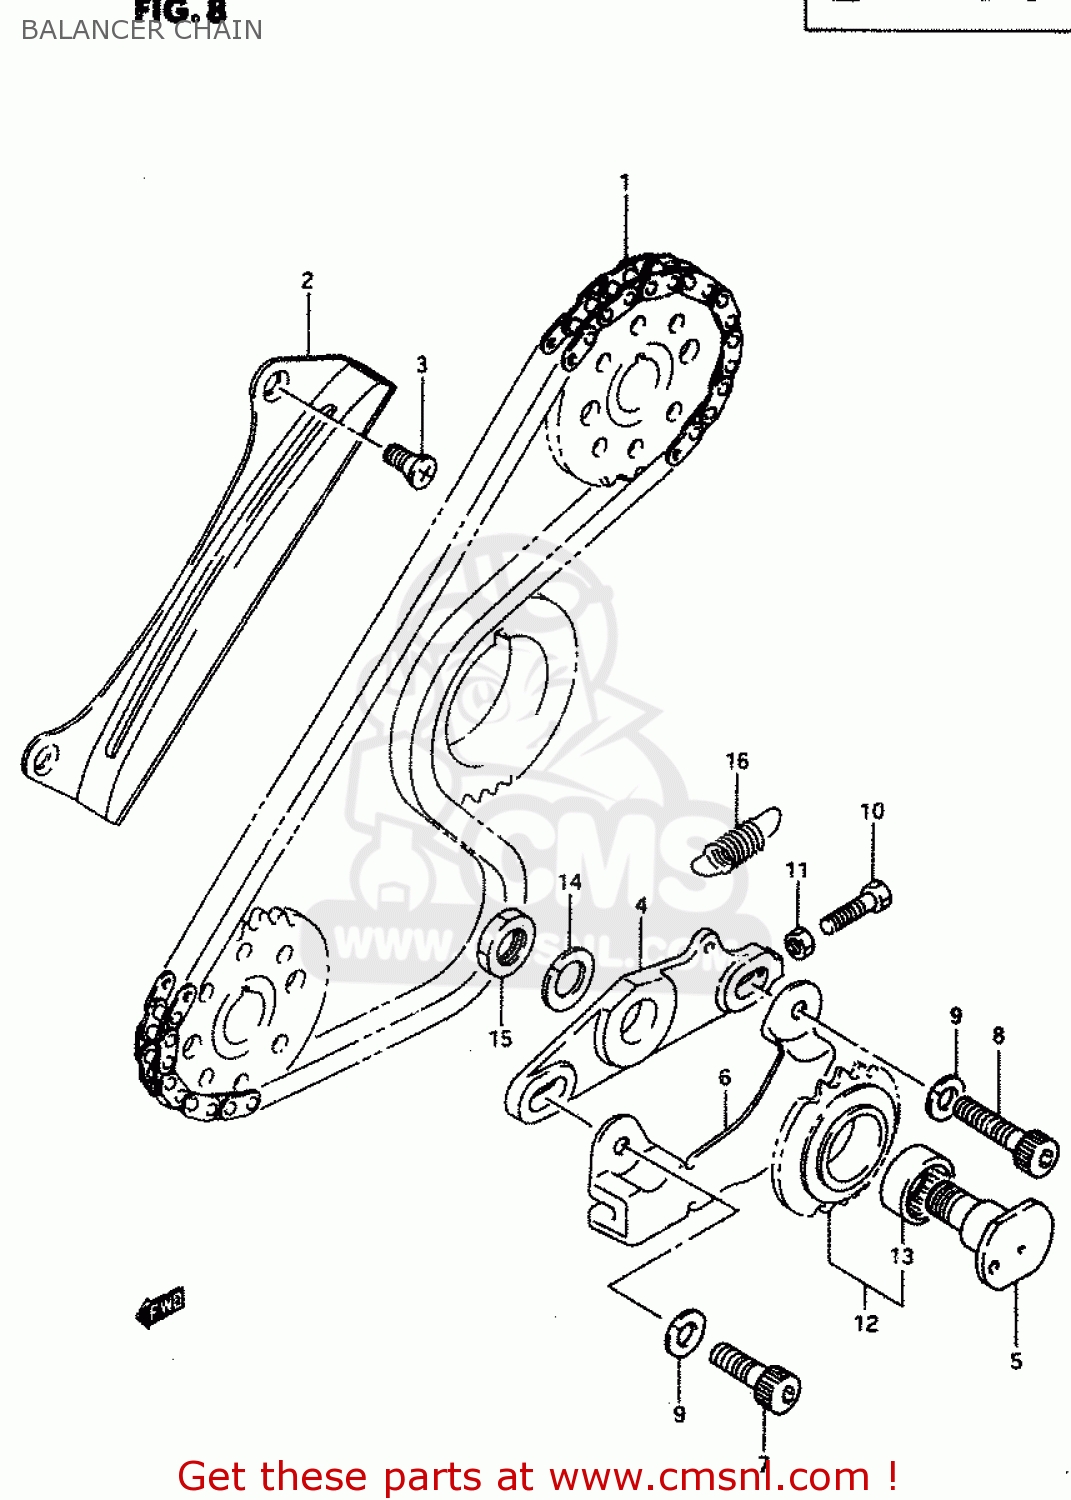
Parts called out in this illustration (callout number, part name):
1	CHAIN,BALANCER
2	GUIDE,BALANCER CHAIN
3	SCREW ,6X16
4	BRACKET,BALANCER CHAIN
5	SHAFT,BALANCER CHAIN TENSIONER
6	GUIDE,BALANCER CHAIN TNSN
7	BOLT(8X22)
8	BOLT
9	LOCK WASHER
10	BOLT
11	NUT
12	SPRKT,BALANCER CHAIN TENSIONER
13	BEARING(17X23X12)
14	WASHER,LOCK
15	NUT
16	SPRING
